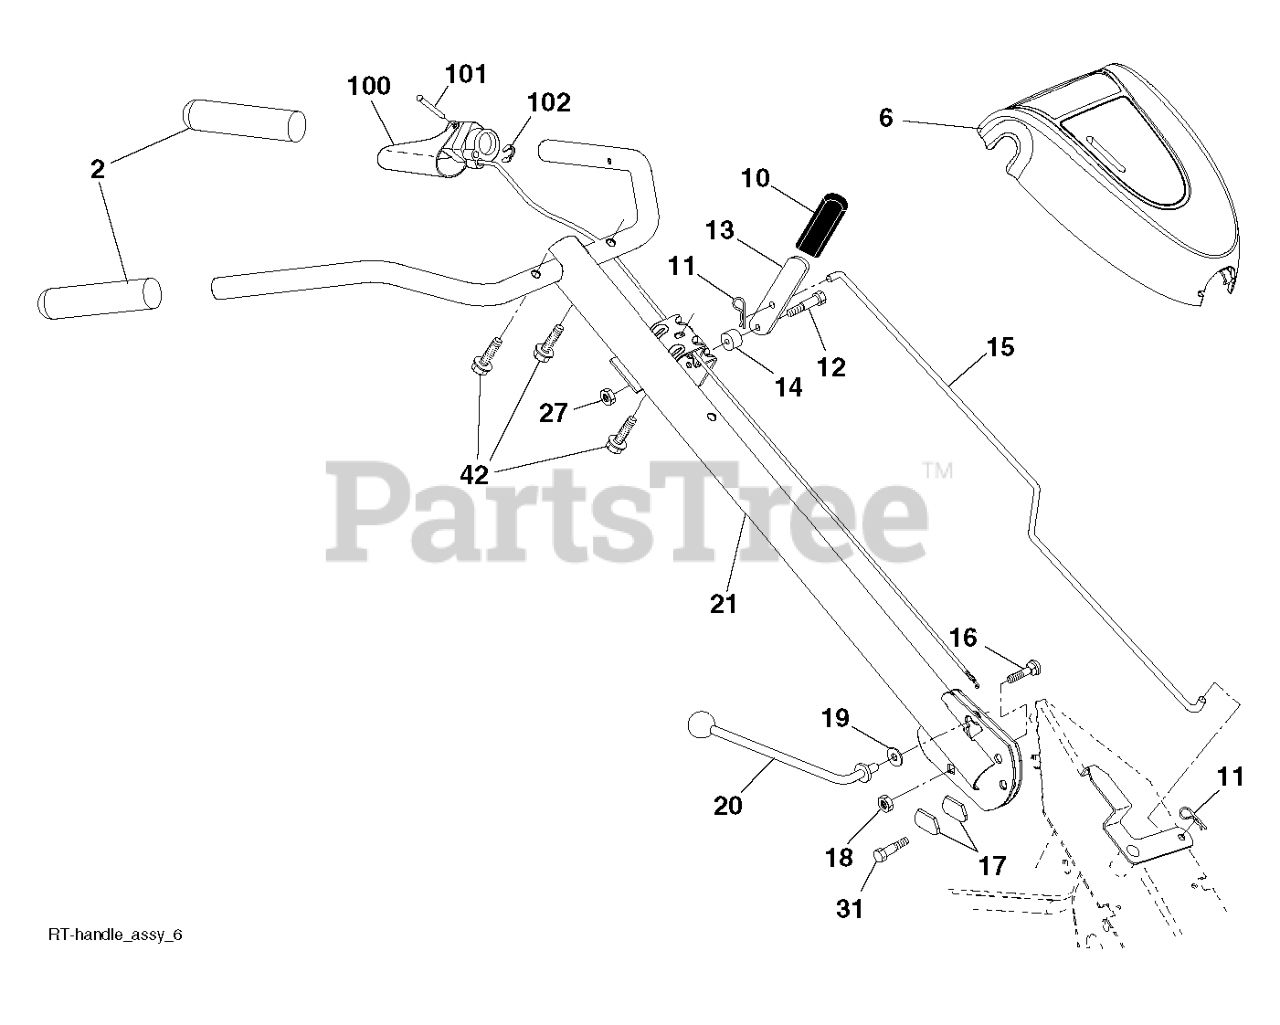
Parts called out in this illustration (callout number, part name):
2	GRIP.1X5.06
6	CONSOLE HUSQVARNA W/O THROTTLE
10	GRIP HANDLE TILLER RED
11	RETAINER M
12	SHOULDER BOLT ST
13	HANDLE
14	GROMMET.RUBBER.CRT.TILLER
15	ROD SHIFT RT UNIVERSAL
16	BOLT D
17	LOCK.HANDLE.CRT
19	WASHER CRT
20	LEVER.LOCK.CRT
21	HANDLE.ASM.HUSQ/P.PRO.GREY
27	NUT T
31	BOLT.PIVOT
42	SCREW.#10 X 0.750.BOS
100	CONTROL.ASSEMBLY.TINE.TILLER
101	PIN, PIVOT
102	RETAINING.RING.#5103-25
